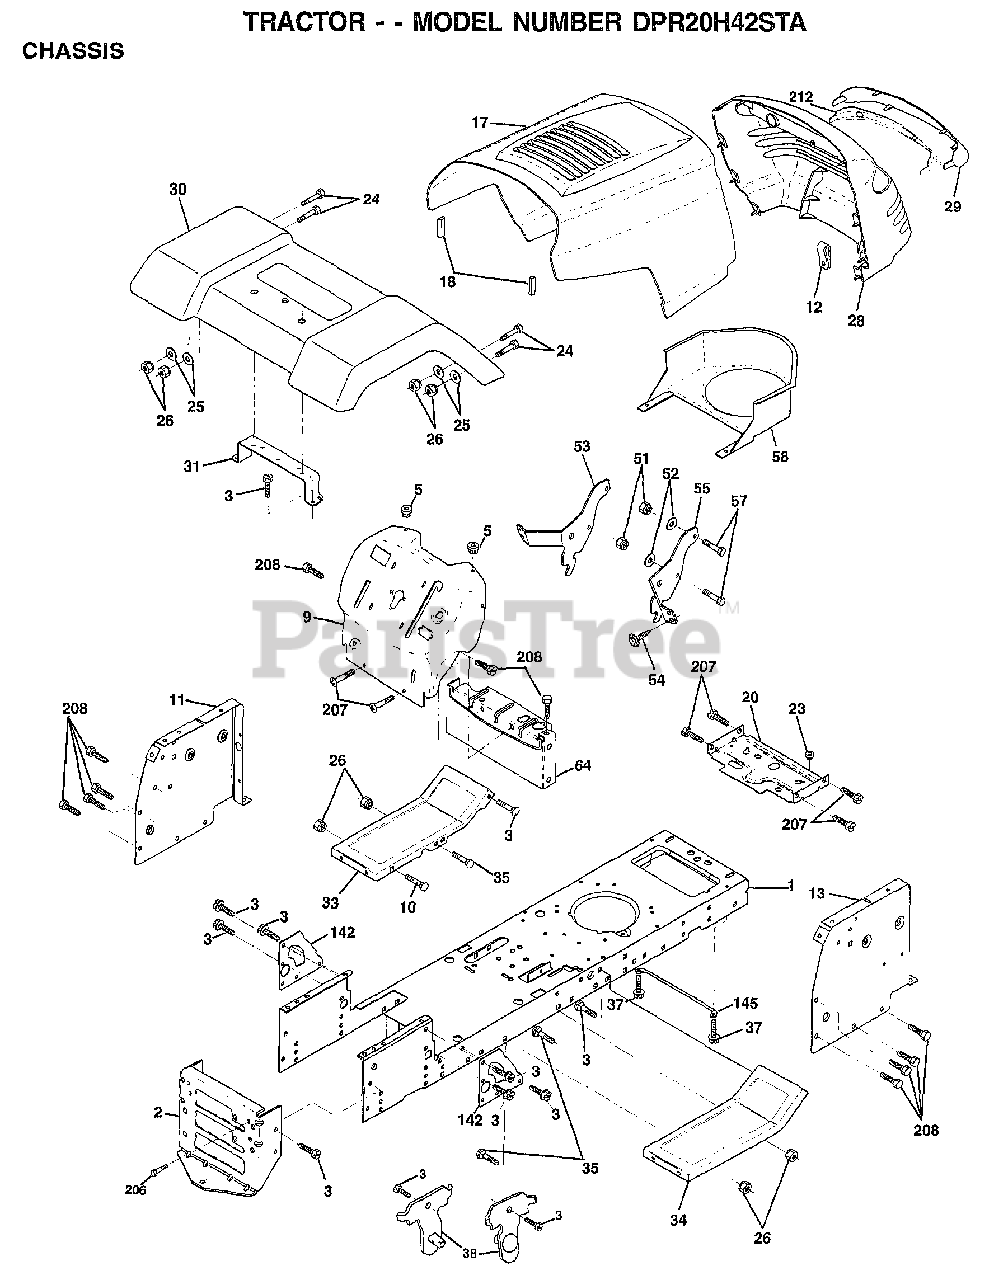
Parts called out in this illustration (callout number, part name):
1	CHASSIS
2	DRAWBAR
3	SCREW
5	BUMPER-HOOD/DASH
9	DASH
11	"PANEL-DASH,LH"
12	CLIP.TINNERMAN
13	PANEL DASH
17	"HOOD W/TRIM,MS428"
20	"PLATE-MTG,BATT/FU"
24	BOLT
25	WASHER
26	NUT
28	GRILLE
29	LENS
30	FENDER FOOTREST
31	BRKT FENDER
33	FOOTREST PNT LH
34	FOOTREST.RH.LT/GT
35	BOLT
37	SCREW LT
38	BRKT ASM PIVOT MOWER REAR
51	NUT
52	WASHER
53	BRACKET.GRILLE.LH
54	SCREW.HEX.WS.HD
55	BRACKET.GRILLE.RH
58	DUCT.AIR.B&S.18HP
64	DASH-LOWER
142	PLATE.REINFORCEMENT
145	"ROD POVOT,CHASSIS"
206	BOLT SHOULDER
207	SCREW
208	SCREW
212	INSERT LENS REFLECT
